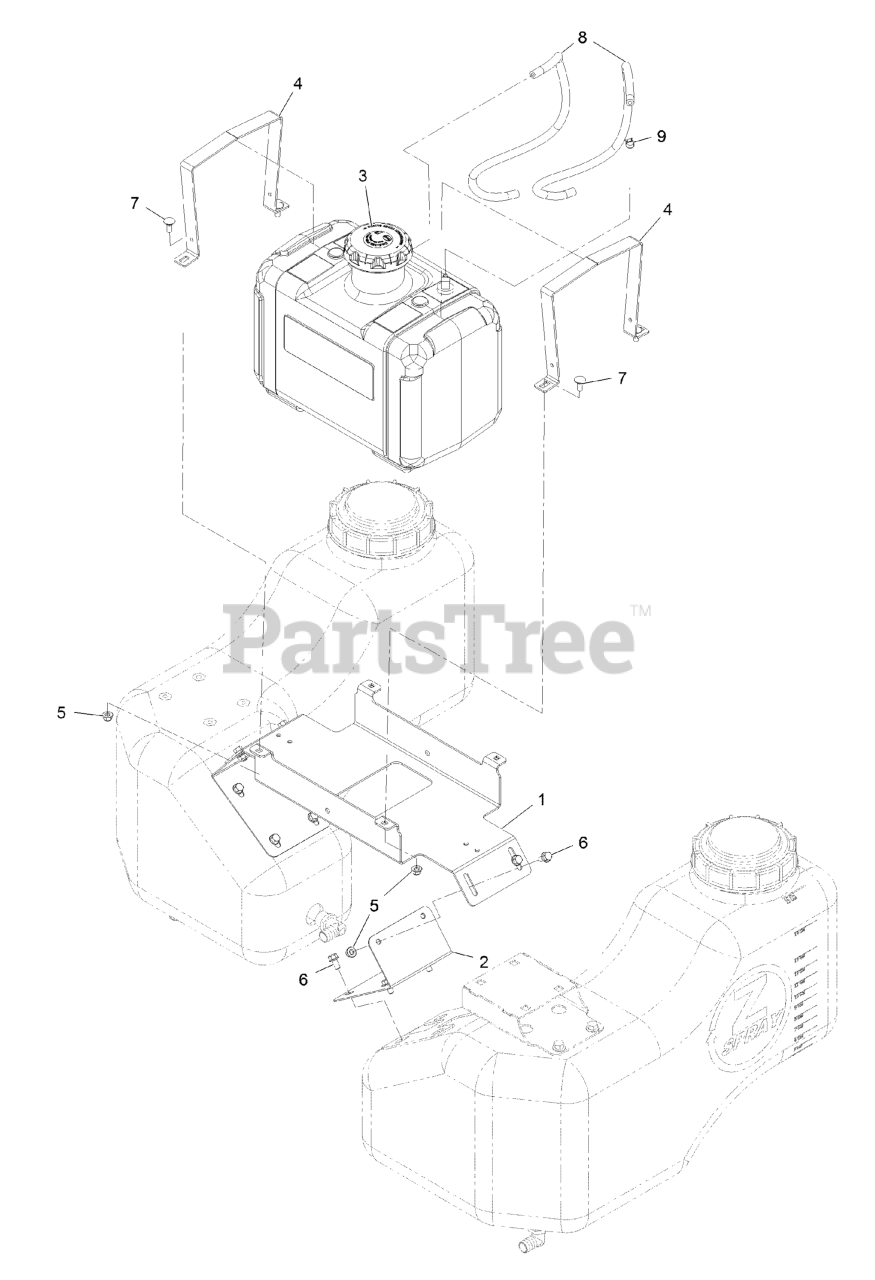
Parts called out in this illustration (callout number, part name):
1	Mount, Gas Tank
2	BRACKET-SUPPORT, GAS TANK
3	ASM-Tank, 5 Gal.
4	Strap, Gas Tank
5	Nut-Hex Flange
6	Screw-HHF
7	SCREW-CARR
8	HOSE-FUEL
9	CLAMP-HOSE
